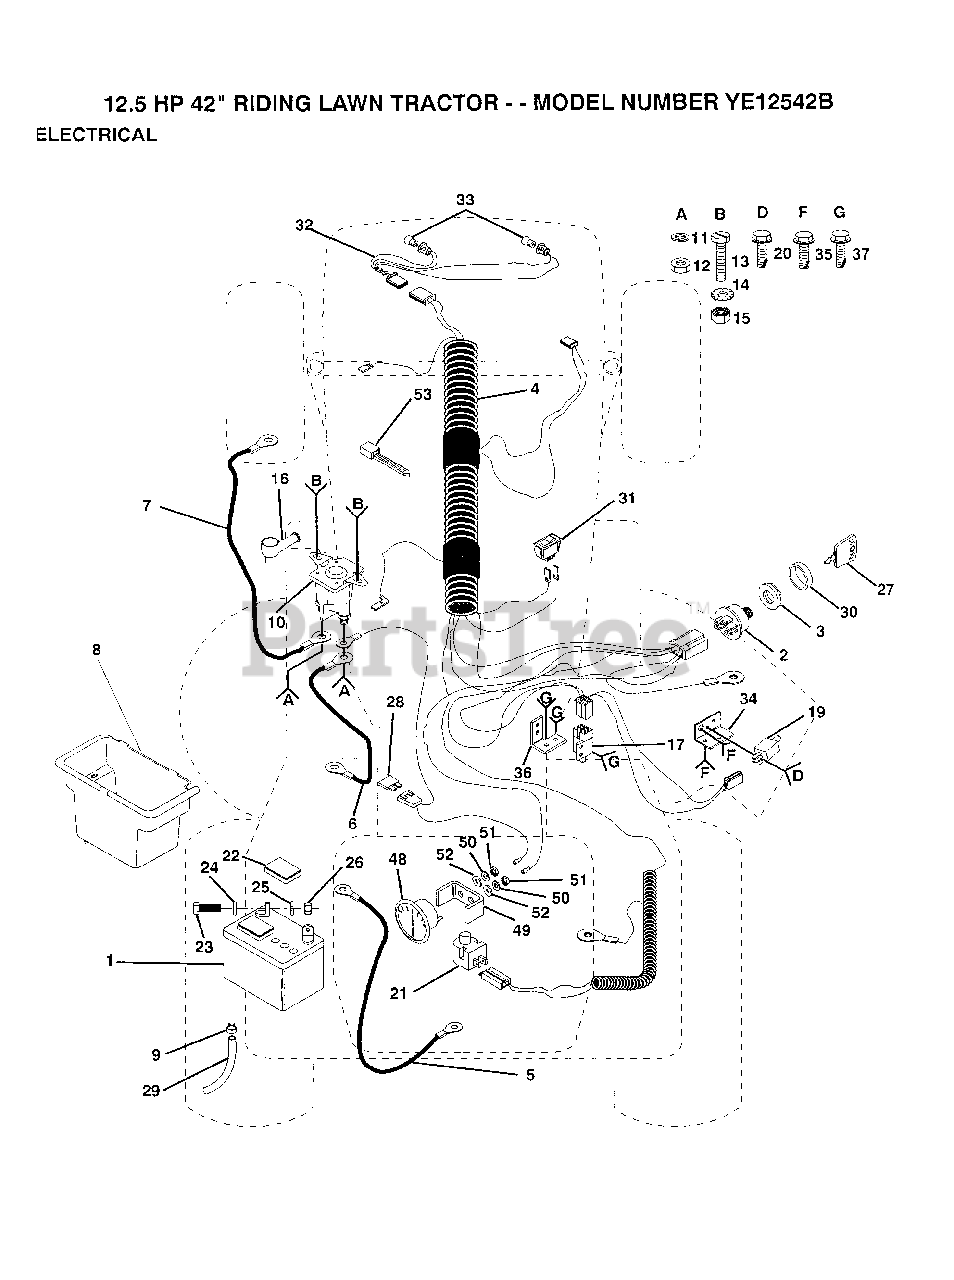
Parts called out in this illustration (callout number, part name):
3	NUT IGNITION
4	IGNITION HARNESS
5	CABLE T
6	STARTER CABLE GT
7	"CABLE T, BATTERY"
8	BTRY CASE W/O LID
9	HOSE CLAMP T
12	NUT
13	BOLT
15	NUT
17	SWITCH INTERLOCKT
19	SWITCH-INTER. GT
20	SCREW
21	SWITCH SEAT
22	"CAP,BATTERY "
23	BOLT LT
24	WASHER
25	LOCKWASHER
27	KEY
28	FUSE HYT
31	SWITCH LT
34	BRACKET LT
35	SCREW
36	SWITCH BRACKET
37	SCREW
48	AMMETER T
52	WASHER
53	WIRE TIE
